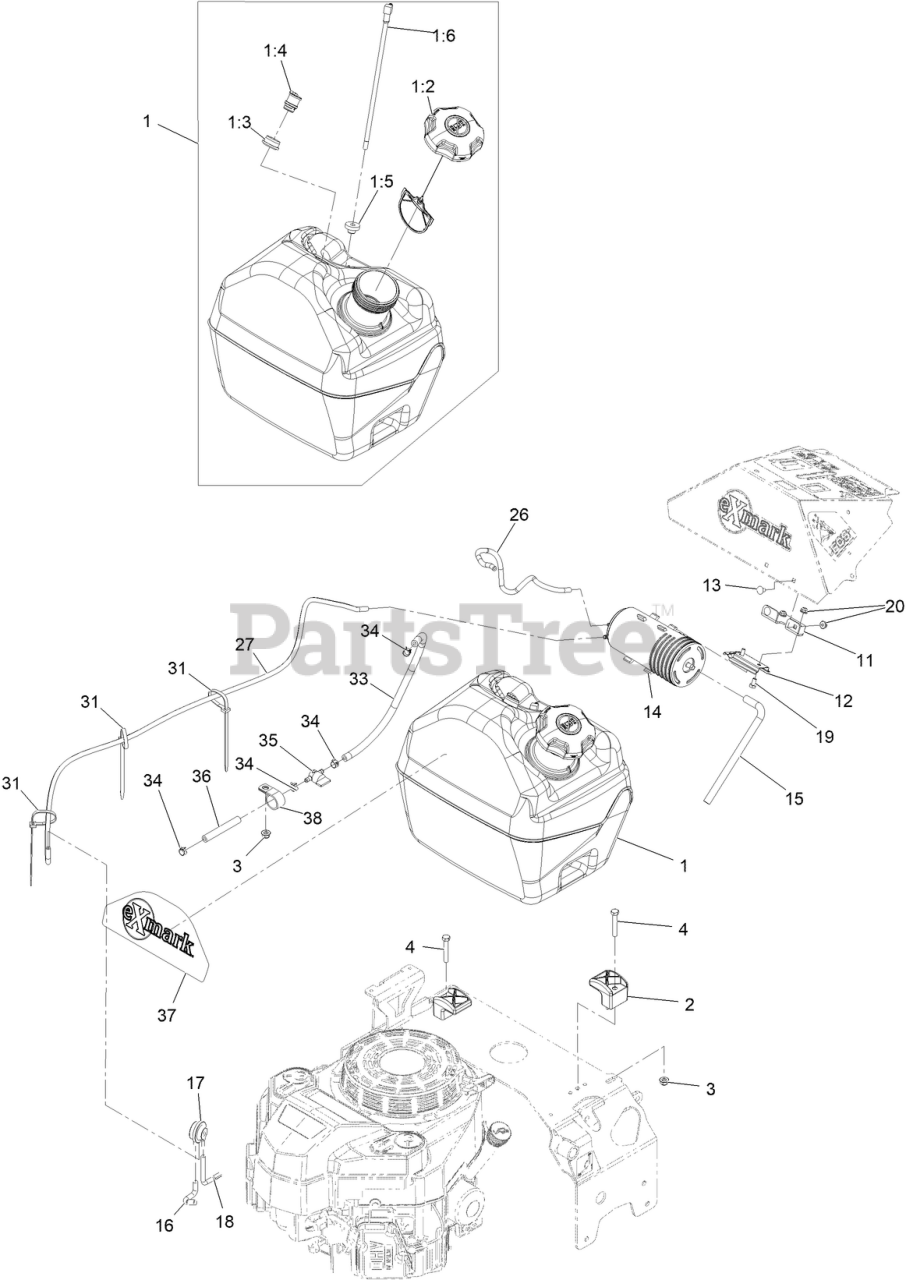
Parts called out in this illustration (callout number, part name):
1	Fuel Tank ASM, 5 Gal
1:2	CAP-FUEL, RATCHETING
1:3	GROMMET
1:4	VALVE-VENT, FUEL
1:5	BUSHING
1:6	FITTING, FUEL W/LINE AND SCREEN
3	NUT-HF, NI
4	SCREW-HH
11	BRACKET-CANISTER, CARBON
12	BRACKET-CANISTER, CARBON
13	SCREW-CARR
14	CANISTER-CARBON, 800CC
15	HOSE-VENT, CANISTER
16	HOSE-VENT, FORMED
17	VALVE-CONTROL, VACUUM
18	HOSE-VENT, FORMED
19	SCREW-HH
26	HOSE-EMISSIONS
27	HOSE-VENT, FORMED
31	TIE-CABLE
33	HOSE-FUEL
34	CLAMP-HOSE
35	VALVE-FUEL
36	HOSE-FUEL
37	Artwork-Exmark Logo Fuel Tank
38	CLIP-LOOM
